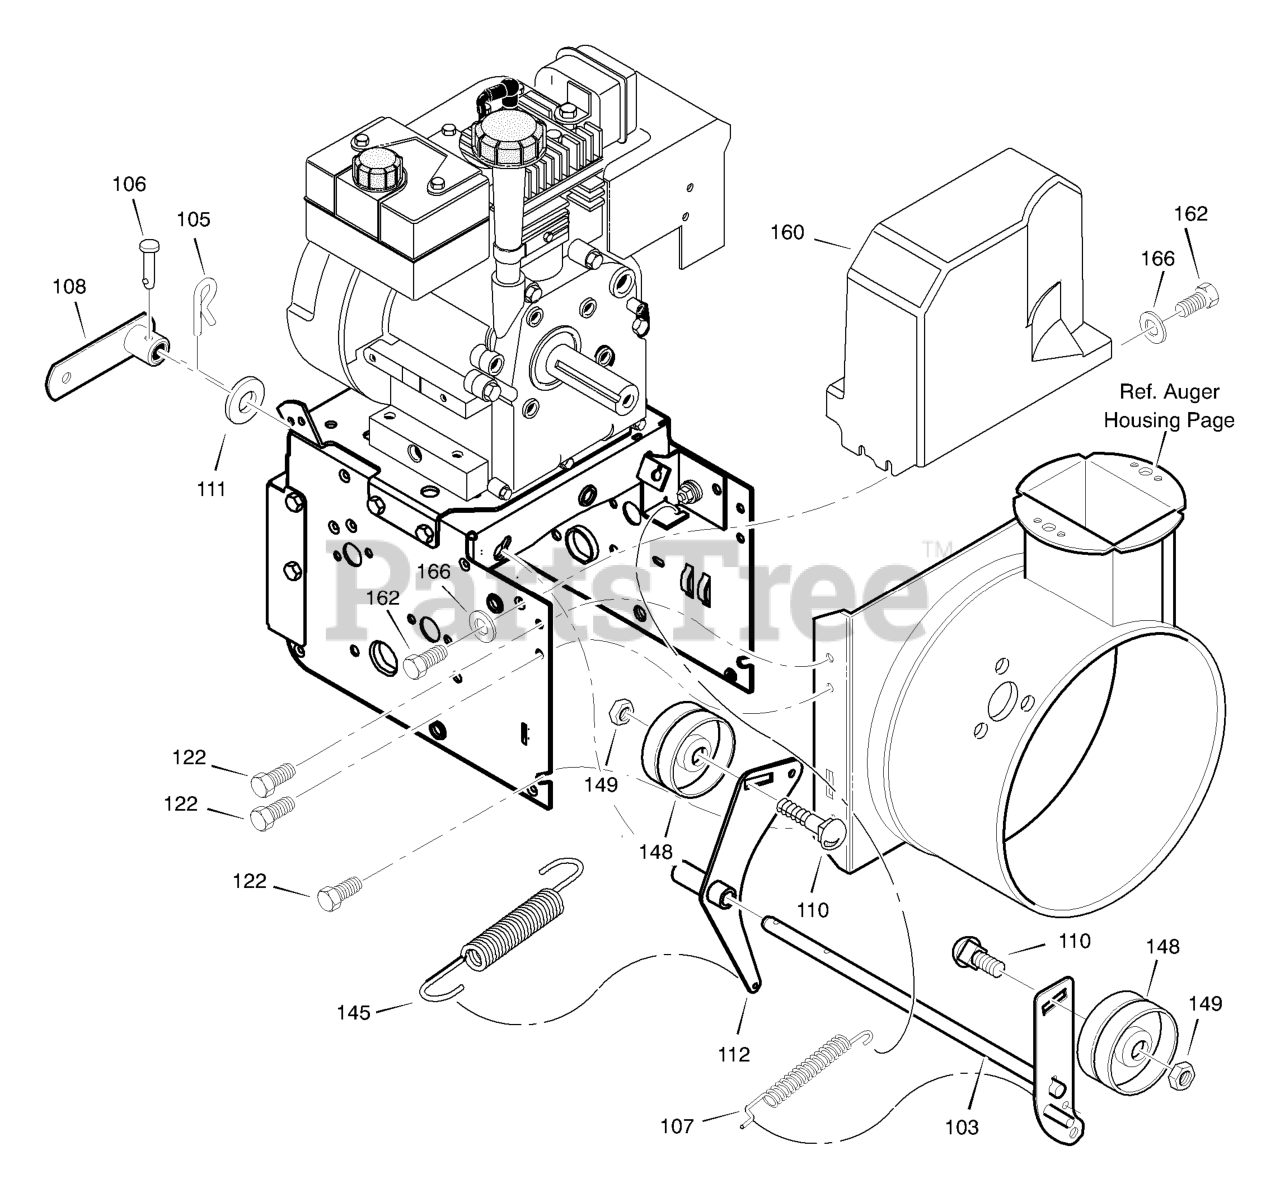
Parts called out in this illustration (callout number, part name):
103	IDLER ASSEMBLY, AUGER
105	PIN, HAIR .38DIAX1.64LG
106	PIN, CLEVIS 3/16" DIA
107	SPRING, TENSION
108	ASSY., SPRING ATTACH
110	BOLT, 3/8-16X1.25 CARR.
111	WASHER, FLAT
112	BRACKET, IDLER
122	SCREW, TAP 5/16-18 X .50
145	SPRING, CLUTCH
148	PULLEY, IDLER
149	NUT, JAM 3/8-16
160	COVER, BELT
162	SCREW, TAP
166	WASHER, FLAT
